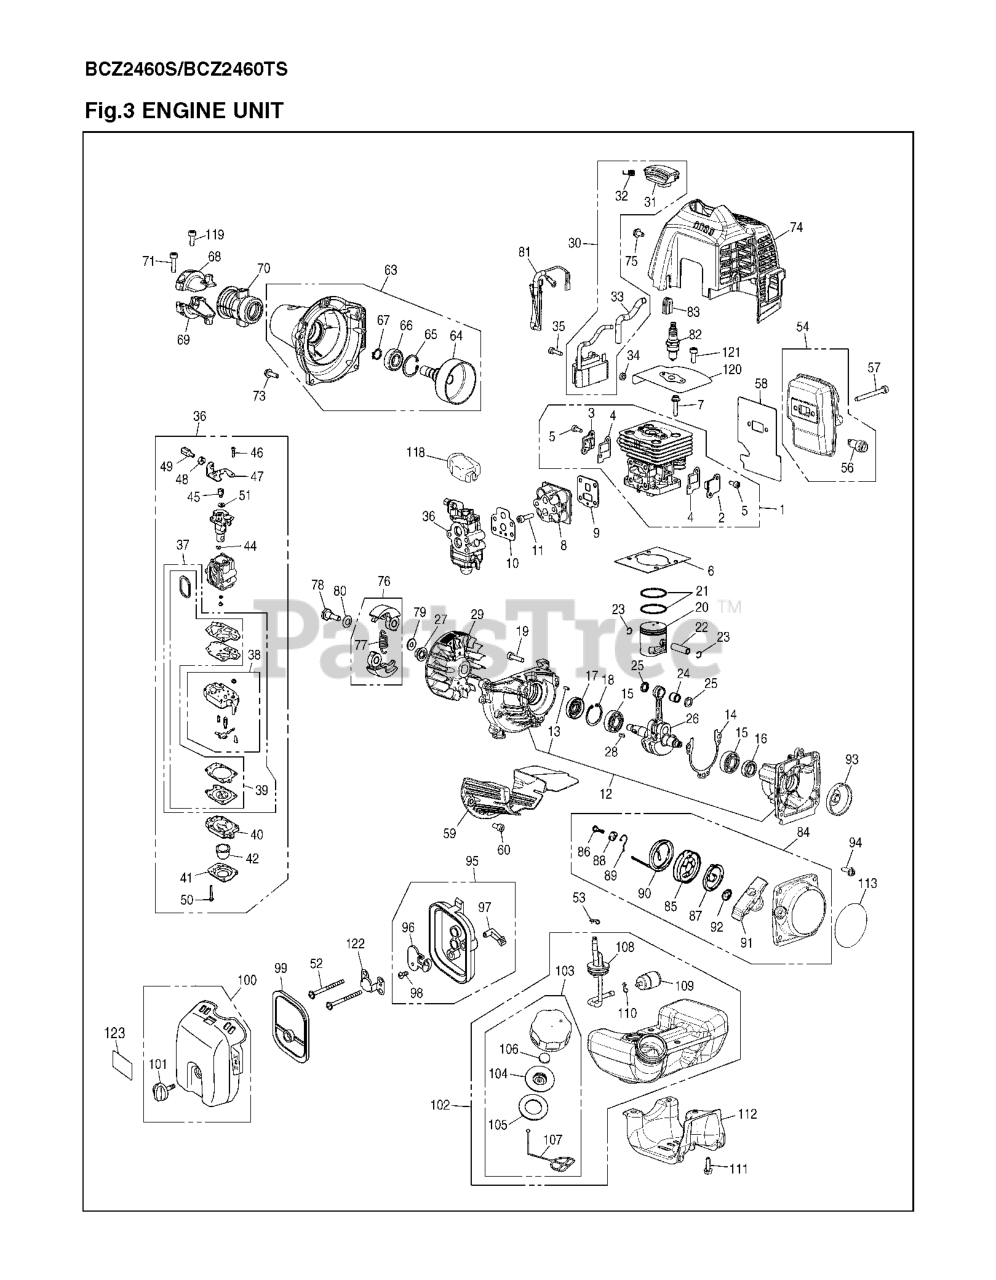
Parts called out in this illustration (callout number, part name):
1	CYLINDER COMP
2	COVER, TR-S
3	COVER, TR-F
4	GASKET, TR
5	SCREW
6	GASKET, BASE
7	BOLT
8	INSULATOR
9	INSULATOR GASKET(R-848F0814B0)
10	GASKET, CARB
11	BOLT TORX
12	CRANKCASE-C
14	GASKET, CASE
16	SEAL
17	OIL SEAL
19	SCREW
22	PIN, PISTON
23	RING, SNAP (RPLS 110141320)
25	WASHER
26	CRANKSHAFT-C
27	NUT(RPLS 1140-43230&182301)
28	KEY
30	COIL ASSY
34	RP_SPACER (RPLS 1260-71260)
35	RP_BOLT TORX
36	CARBURETOR ASSY
37	REBUILD KIT
38	BODY, PUMP
39	GASKET KIT
40	BODY, PURGE
41	RP_COVER, PUMP
42	RP PUMP, PRIMING
45	RP_SWIVEL
46	RP_SCREW
48	%NUT CABLE 506612601***
49	%ADJUSTER 506613601***
50	SCREW
51	WASHER
52	BOLT TORX
53	CLIP
54	MUFFLER
56	ARRESTER
57	BOLT
58	GASKET, MUFFLER
60	BOLT
63	COVER, C
64	DRUM (RPLS 481031120-22)
68	BRACKET (A) (RPLS T170031211)
69	BRACKET (B)
70	CUSHION (RPLS T170031231)
71	SCREW
73	BOLT
74	COVER, ENGINE
75	BOLT (RPLS T495051010-11)
76	SHOE COMP
77	SPRING
78	BOLT
79	WASHER
80	WASHER (RPLS 1140-51241)
81	CORD COMP.
82	SPARK PLUG CMR7H-10
83	GROMMET
84	RECOIL-A
85	REEL
86	SCREW
87	SPRING, SPIRAL
88	COLLAR
89	ARM
90	ROPE (RPLS 450075160)
91	KNOB (RPLS 3330-75420)
92	PLATE, STOPPER
93	PULLEY
94	BOLT, TORX
95	CLEANER BODY ASSY
96	PLATE, CHOKE
98	SCREW
99	ELEMENT
100	COVER ASSY
101	Cleaner Knob
102	TANK ASSY
103	CAP ASSY
104	HOLDER (RPLS 450085230)
105	RP_PACKING
106	FILTER
107	STOPPER***
108	PIPE-C
109	FILTER
110	CLIP
111	BOLT
112	GUARD, TANK
113	LABEL, RECOIL
118	COVER
119	BOLT
121	BOLT
123	LABEL
